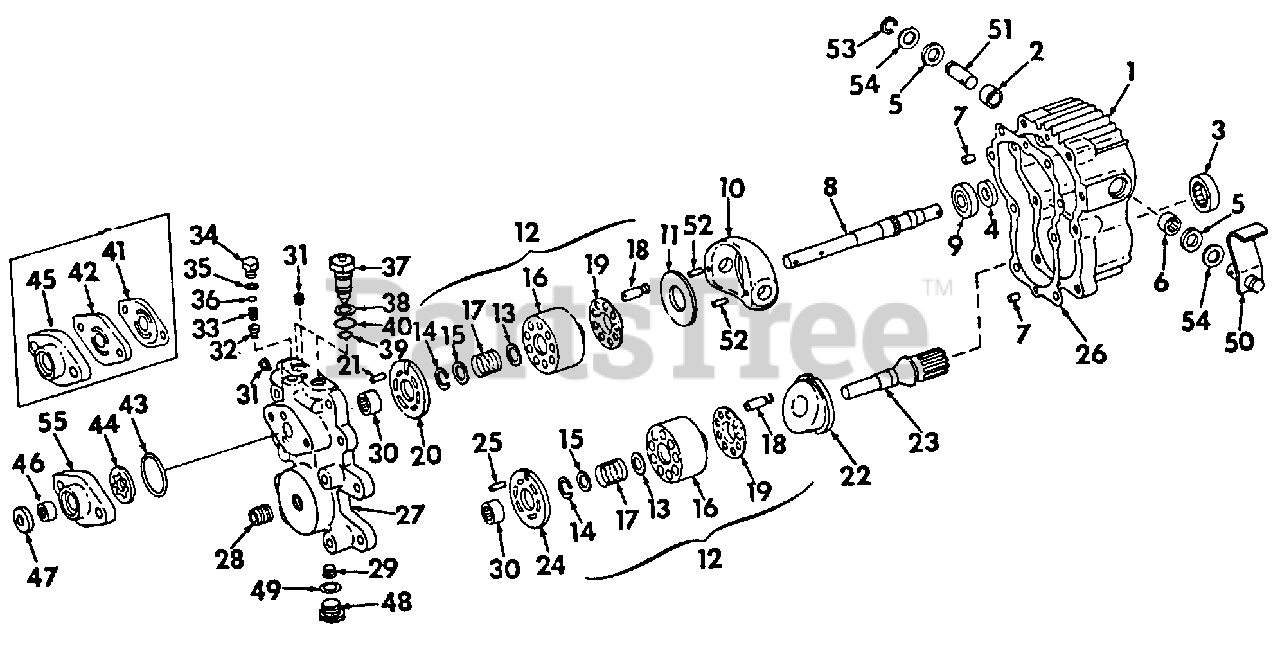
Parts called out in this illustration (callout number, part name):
2	Not used in this application
3	Bearing, Hyd Pump Shaft Roller
4	Seal, Lip
5	Seal, Lip
6	Bearing, Needle
7	Pin, Transmission Housing
8	Shaft, Transmission Hyd Pump
9	Bearing, Ball
10	Swashplate, Hyd Pump
11	Plate, Hyd Pump Swashplate Thrust
12	Kit, Cylinder Block Motor & Pump
13	Washer, Spring Front
14	Ring, Hyd Cylinder Block Spring Rear Washer Snap
15	Washer, Hyd Cylinder Block Spring Rear
16	Not used in this application
17	Spring, Hyd Cylinder Block
18	Not used in this application
19	Retainer, Hyd Piston Slipper
20	Plate, Hyd Cylinder Block Valve
21	Pin, Hyd Pump Cylinder Block
22	Swashplate, Hyd Motor
23	Shaft, Transmission Hyd Motor
24	Plate, Hyd Motor Cylinder Block Valve
25	Pin, Hyd Motor Cylinder Block
26	Gasket, Transmission Housing
27	Housing, Center Section
28	Fitting, Center Housing Oil Filter
29	Plug, 1/4-18 Automotive Hex Soc Hd Pipe
30	Bearing, Center Housing Needle
31	Plug, 1/8-27 Automotive Hex Soc Hd Pipe
32	Cone, Charge Pump Relief Valve
33	Spring, Charge Pump Relief Valve
34	Plug, Charge Pump Relief Valve
35	O-Ring, 13/32 X 9/16 X 5/64 Relief Valve Plug
37	Valve Assy, Center Housing Check
38	Washer, Check Valve Housing Back Up
39	O-Ring, 5/8 X 3/4 X 1/16 Check Valve Housing Small
40	O-Ring, 3/4 X 15/16 X 3/32 Check Valve Housing Large
41	Not used in this application
42	Not used in this application
43	O-Ring, 2-3/8 X 2-1/2 X 1/6 Class 5
44	Rotor Assy, Charge Pump
45	Not used in this application
46	Bearing, Charge Pump Housing Needle
47	Seal, Lip
48	Plug, 3/4-16 C-Z Str Thrd O-Ring Boss Center Hsg
49	O-Ring, 41/64 X 13/16 X 3/32 Center Hsg O-Ring Plug
50	Shaft Assy, Trunnion
51	Shaft, Trunnion
52	Pin, 3/16 X 5/8 Slt Spring
53	Ring, Trunnion Shaft Snap
54	Washer, Trunnion Shaft Seal Retaining
55	Housing, Charge Pump
